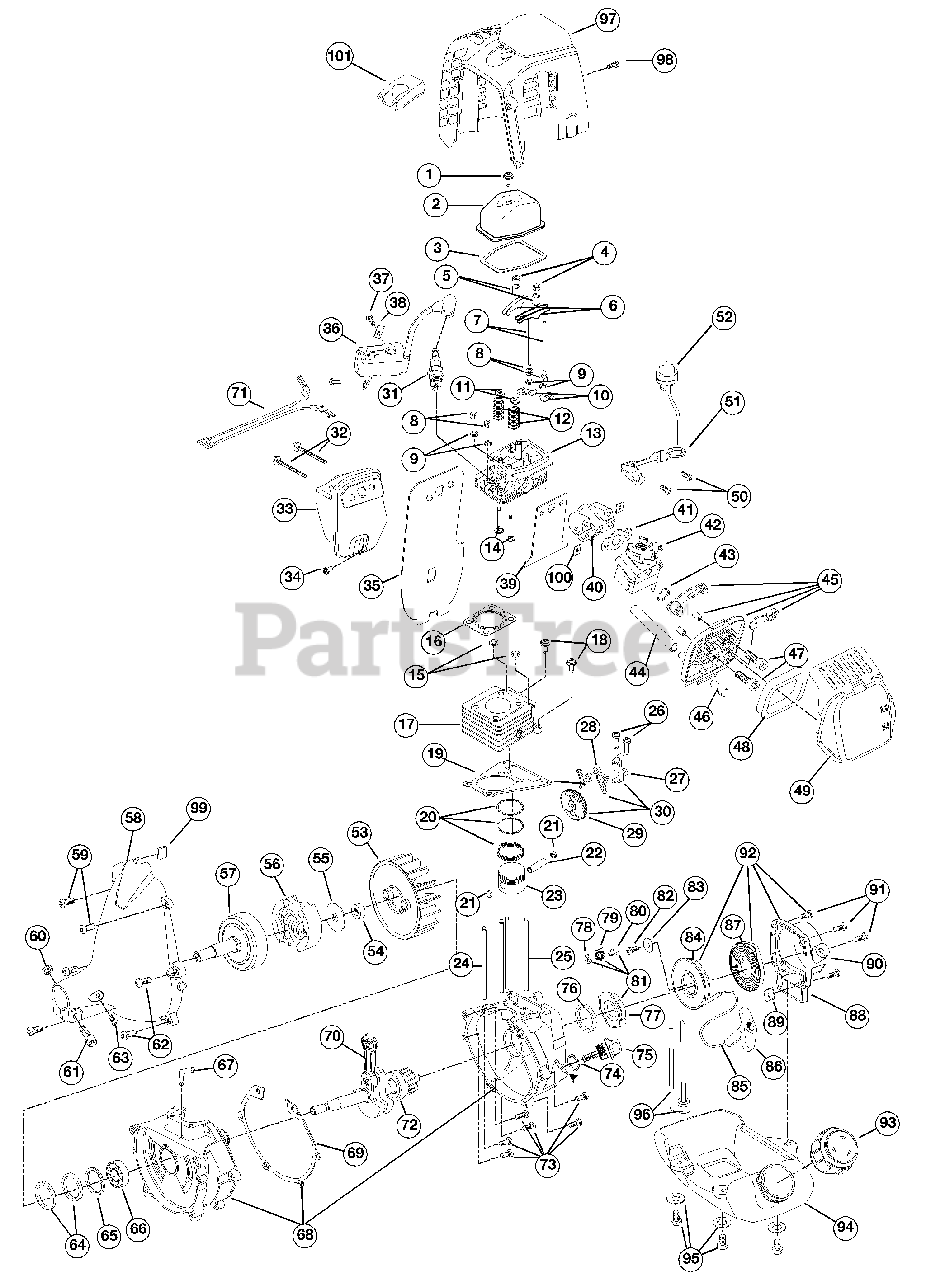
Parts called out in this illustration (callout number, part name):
1	Valve Cover Screw
2	Valve Cover
3	Valve Cover Gasket
4	Rocker Adjustment Nut
5	Rocker Arm Pivot
7	Push Rod
8	Hex Nut
10	Push Rod Guide
11	Valve Spring Retainer
12	Valve Spring
13	Cylinder Head w/Valve Seal (includes 10-14)
16	Cylinder Head Gasket
18	Screw (M5 x 18.7mm)
19	Cylinder Gasket
20	Piston Ring Set (3 Piece Oil Ring)
21	Wrist Pin Button
23	Piston (3 Piece Oil Ring)
24	Cylinder STud(83.5mm)
25	Cylinder STud(115.5mm)
26	Cam Bracket Screw
27	Cam Bracket
28	Cam Follower (Chromed)
29	Cam Gear
30	Cam Bracket Assembly (includes 26-29)
31	Spark Plug
32	Muffler Mounting Screw
34	Spark Arrestor Screen
35	Muffler Gasket
36	Module
38	Ground Tab
39	Insulator Gasket
41	Carburetor Gasket
42	Carburetor
43	O-Ring, Carburetor
44	Breather Hose
45	Air Cleaner Assembly
46	Breather assembly
48	Air Filter
49	Air Cleaner Cover
51	Throttle Cable Bracket
52	Primer and Line Assembly
55	Clutch Washer
57	Clutch Drum
58	Clutch Housing
59	Screw
61	Engine Bolt
62	Screw
63	Anti-Rotation Screw
64	Oil Seal
68	Crankcase (includes 69, 72 & 73)
69	Crankcase Gasket
70	Crankshaft
71	Lead Wire
72	Bearing
74	O-Ring
75	Oil Cap Dipstick (includes 74)
77	Pulley with Nut
78	Retaining Ring
80	Ratchet
81	Pulley Assembly (includes 77-80)
84	Recoil Pulley
86	Pull Handle
87	Recoil Spring
88	Recoil Case (includes 82-91)
89	Square Nut
92	Recoil Case Assembly (includes 78-87)
94	Fuel Tank
95	Screw with Washer
96	Fuel Line Assembly
97	Engine Cover
99	Wire Grommet
101	Spark Plug Cover
